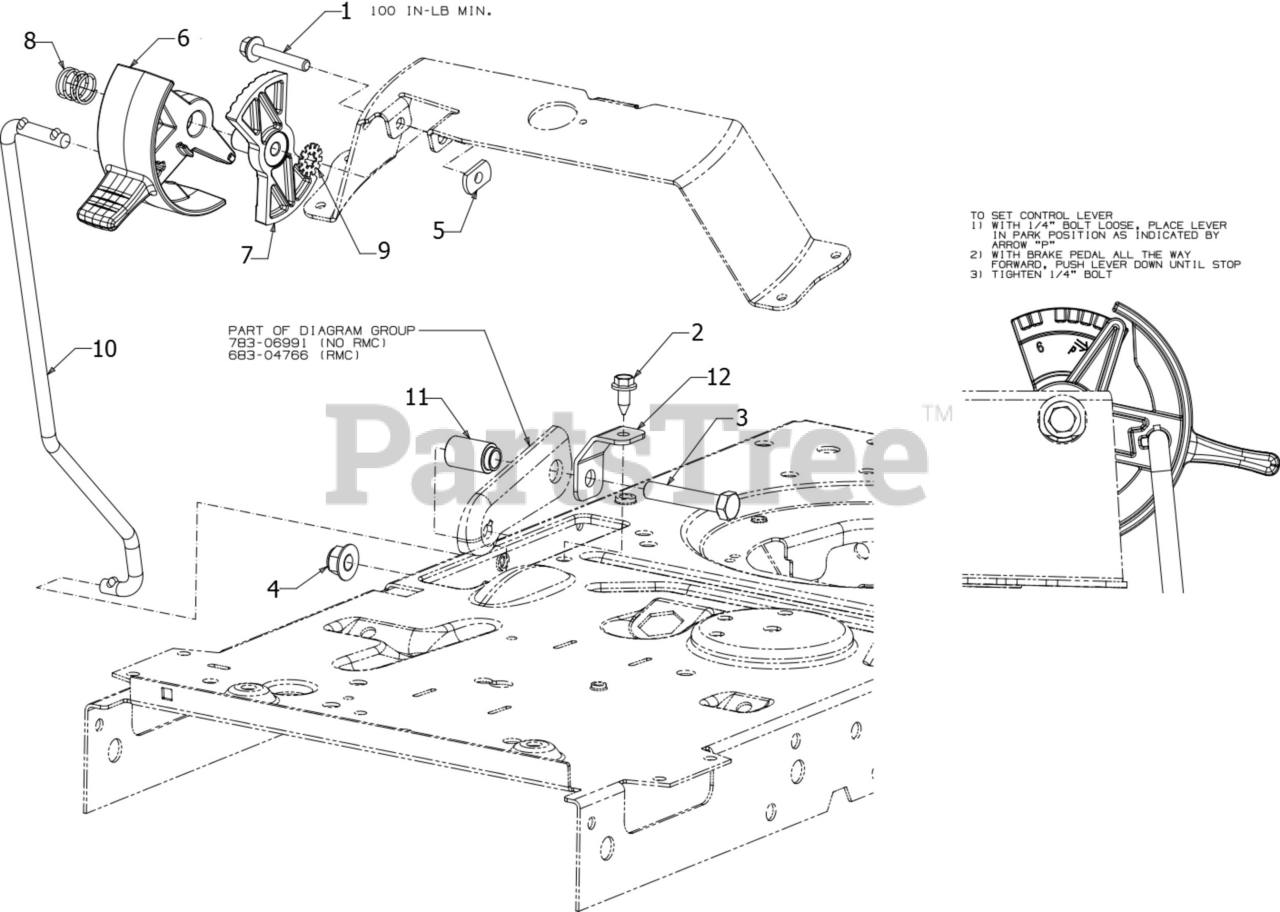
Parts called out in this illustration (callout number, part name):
1	SCREW 1/4-20 x 1.50 GR5
2	SCREW 1/4-20X.625
3	SCREW 3/8-16 x 2.0 GR5
5	FLAT NUT
6	SHIFT LEVER
7	SPEED CONTROL-6 SP
7	INDEX CONTROL 7SPEED
8	COMPRESSION SPRING
9	WASHER
10	SPEED CONTROL ROD
11	FLANGE SPACER
12	SPEED LATCH TAB
